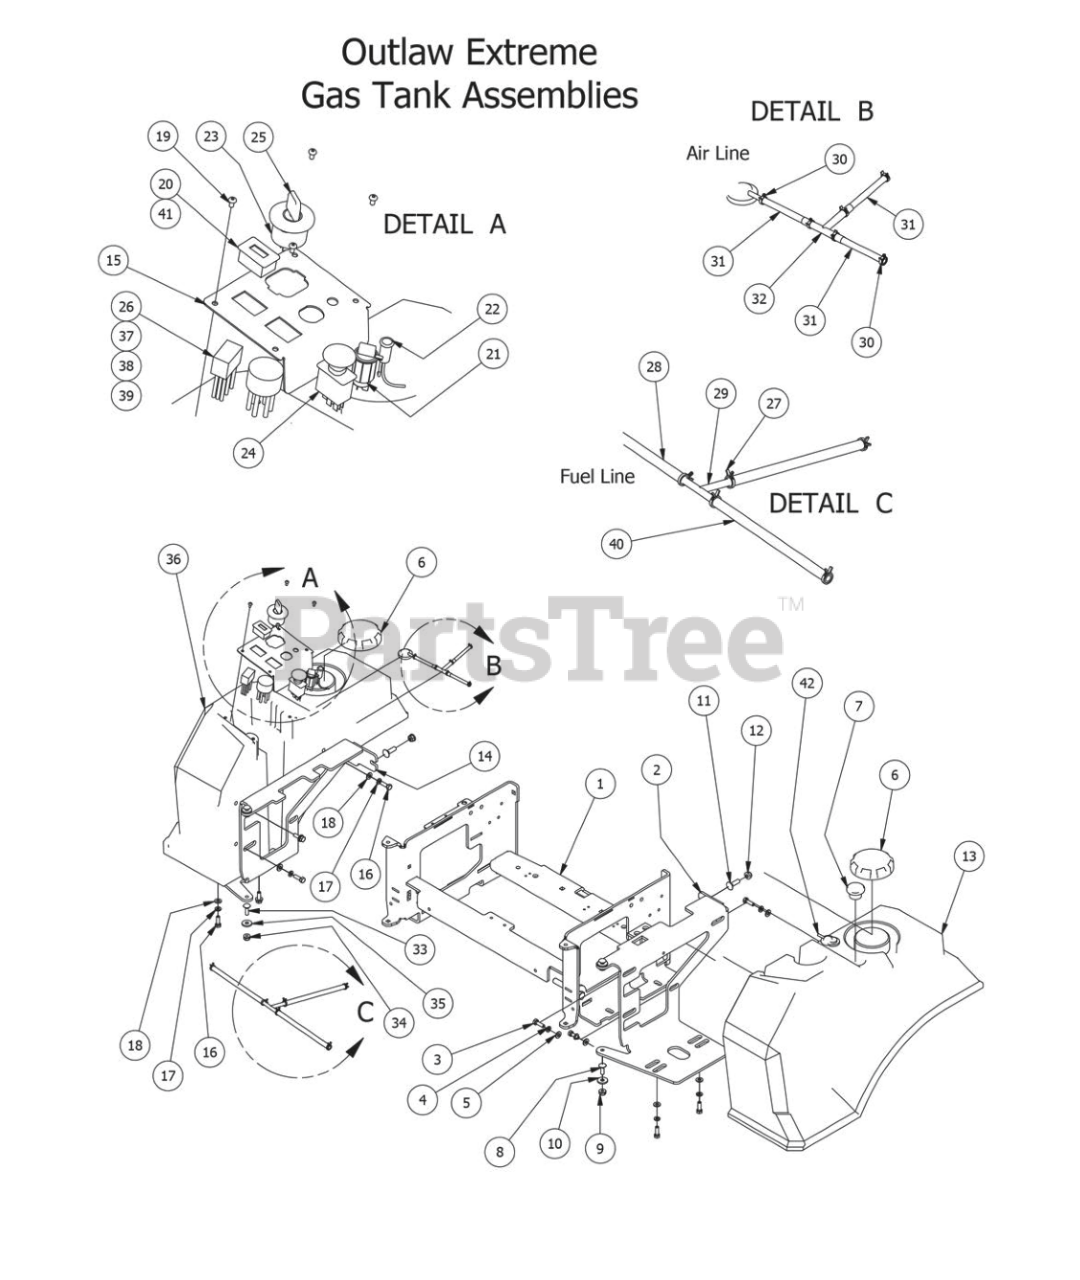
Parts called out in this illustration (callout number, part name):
1	Outlaw Seat Bracket 2012
2	Tank Support 2012 Outlaw (Left)
3	5/16" x 1" Bolt
4	5/16" Lock Washer
5	5/16" Flat Washer
6	3.5" Tethered Fuel Cap
7	Fuel Gauge Tanks W/downtube
8	5/16" x 1" Carriage Bolt
9	5/16-18 Nylon Flange Nut
10	.360 ID Plastic Washer
11	3/8" x 1 1/4" Carriage Bolt
12	3/8" Nylock Flange Nut
13	2012 EPA Fuel Tank- XP-XTRM- Left
14	Outlaw Tank Support 2012 (Right)
15	Outlaw Instrument Panel 2010
16	5/16" x 1" Bolt
17	5/16" Lock Washer
18	5/16" Flat Washer
19	10-32 x 3/8" Button Socket Head Bolt
20	Tachometer
21	12V AUX Connection
23	Ignition Switch
24	PTO Engager
25	Ignition Key
26	Wiring Harness-993cc Outlaw-Vanguard
27	1/4 fuel clamp
28	1/4" fuel line hose
29	fuel line T
30	3/16 vinyl clamp
31	1/4" vinyl tubing
32	fuel line T
33	5/16" x 1" Carriage Bolt
34	5/16-18 Nylon Flange Nut
35	.360 ID Plastic Washer
36	2012 EPA Fuel Tank - XP-XTRM - Right
37	Wiring Harness - 852cc Kawasaki
38	Wiring Harness - 29EFI Kohler
39	Relay Terminal
40	Fuel line assembly
41	Tachometer-2012 29hp EFI Kohler (only)
42	Rollover Valve-White
